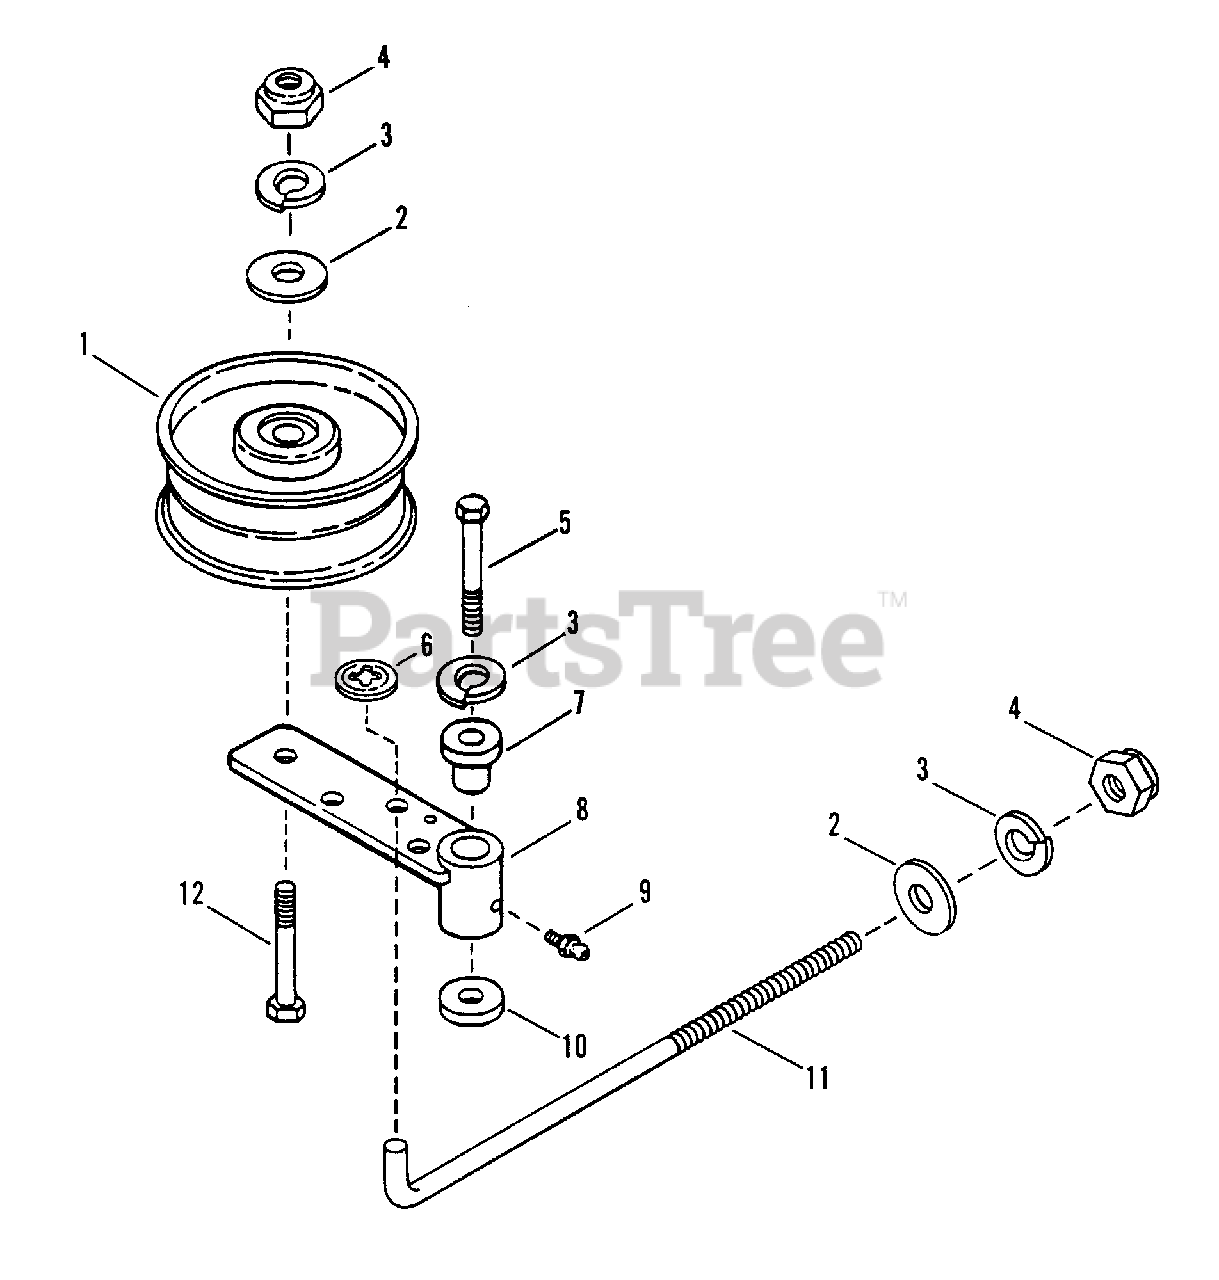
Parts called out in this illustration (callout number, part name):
1	PULLEY, Idler, 5.25
2	WASHER, 3/8" Flat
3	WASHER, 3/8 Lock
4	NUT, 3/8 Nyloc
5	BOLT, 3/8 - 16 x 3" HHC
6	RETAINER, 3/8
7	SPACER, Pivot
8	WELDMENT, 48" Blade/Blade
9	FITTING, Lube
10	BUSHING
11	ROD, 11.25"
12	SCREW, 3/8-16 x 2" Hex Head Cap
